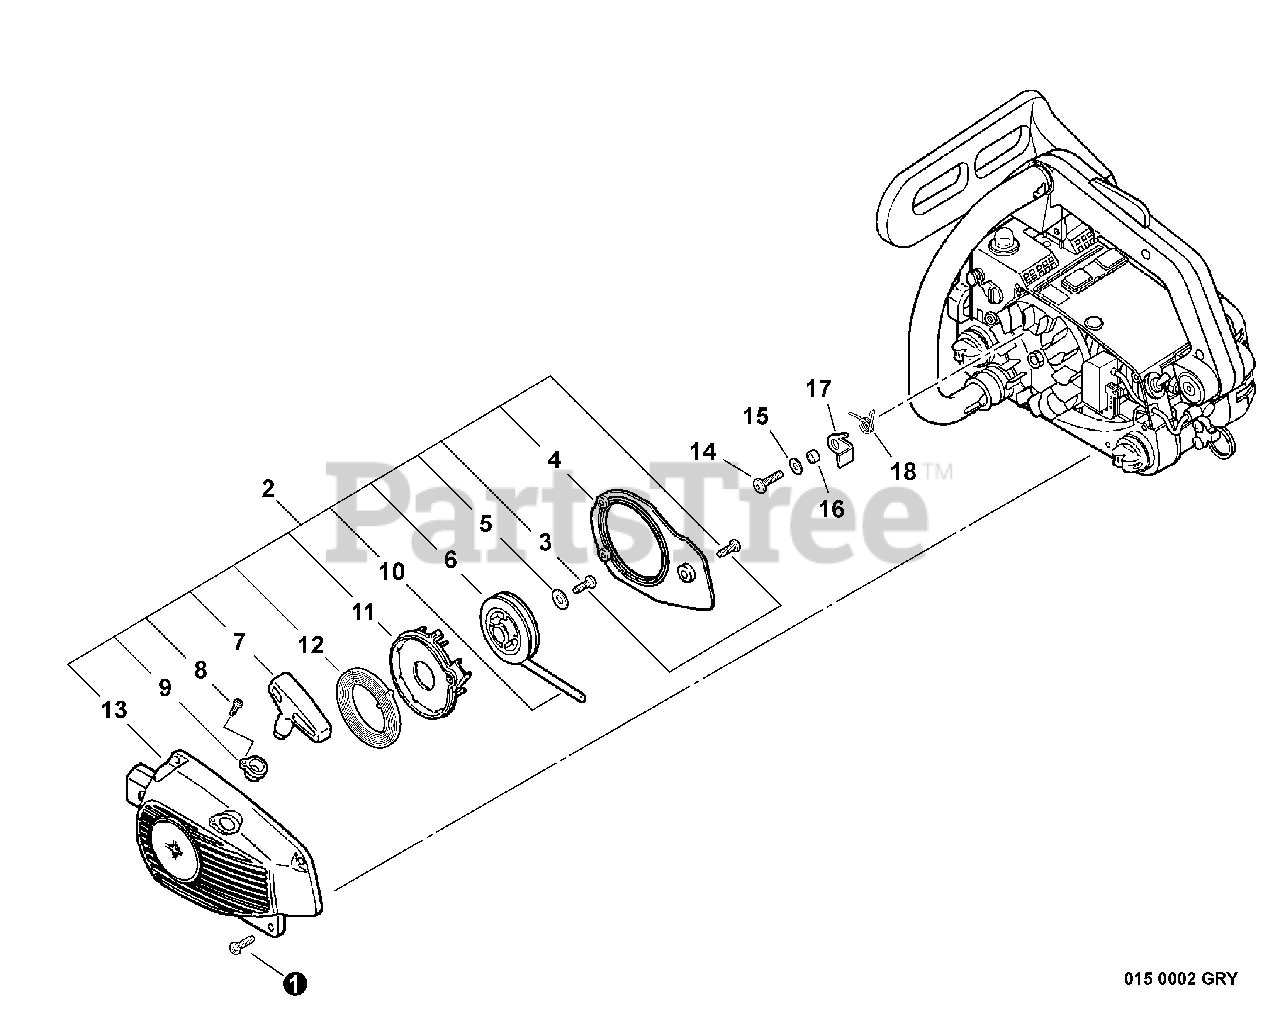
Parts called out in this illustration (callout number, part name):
1	SCREW - 4X16
2	STARTER ASSY
3	SCREW - 4X14
6	REEL, ROPE
7	GRIP, STARTER
8	SCREW - 3X14
9	GUIDE, ROPE
10	ROPE, STARTER - 3X850
11	PLATE, STARTER
12	SPRING, REWIND
13	CASE, STARTER - GRAY
14	SCREW - 5X12
15	WASHER - 5
17	PAWL, STARTER
18	SPRING, RETURN
